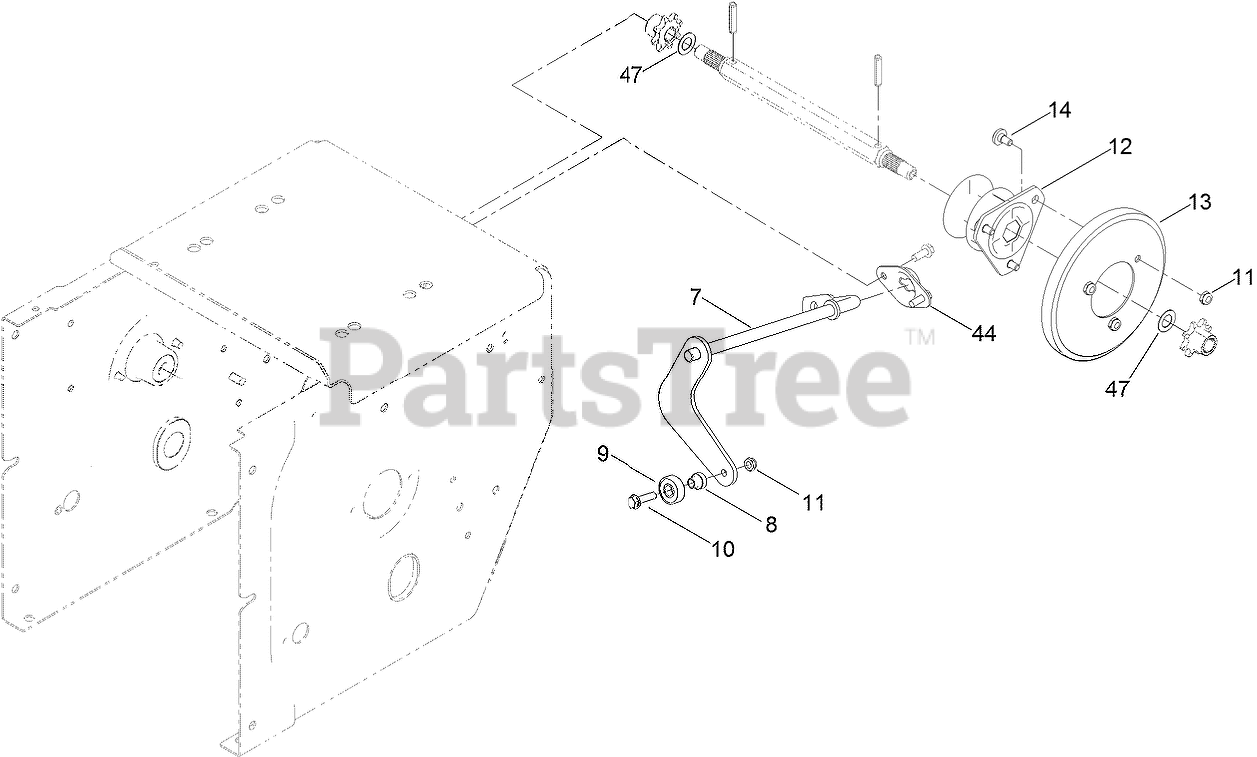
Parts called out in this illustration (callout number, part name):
7	ROD-SHIFT
8	SPACER-PLATE, SHIFT
9	BEARING-BALL
10	SCREW-HWHTF
11	NUT-HEX
12	TRUNNION
13	WHEEL-FRICTION
14	SCREW-SHOULDER
44	RETAINER-ROD, SHIFT
47	WASHER-PLAIN
